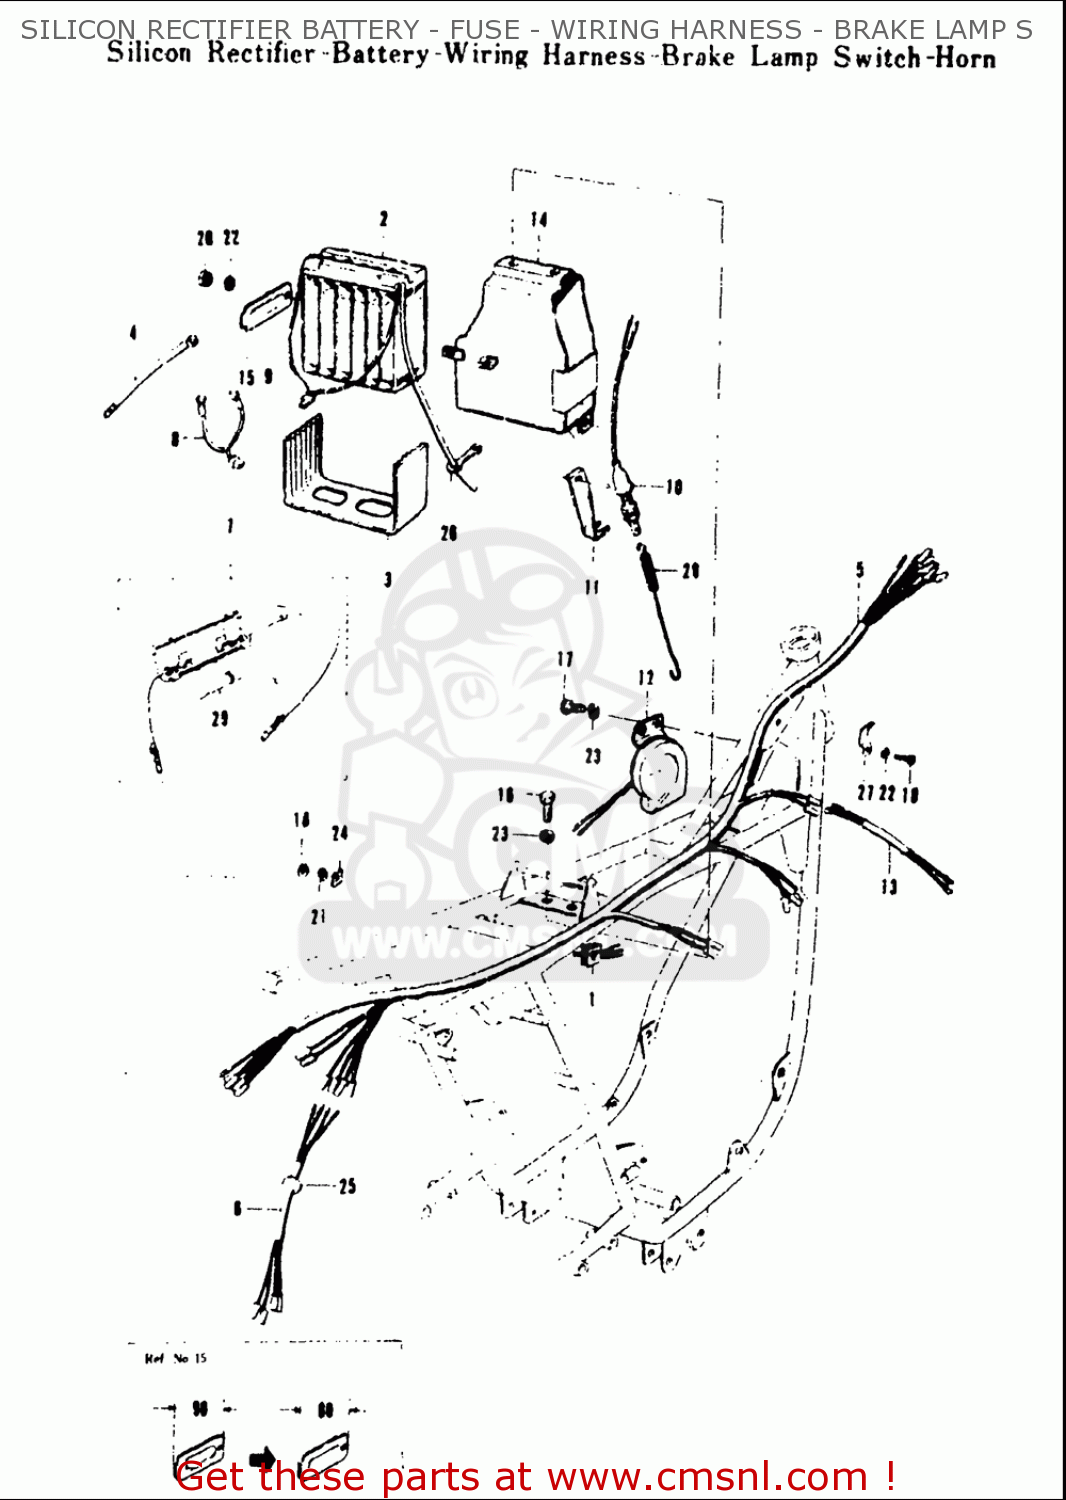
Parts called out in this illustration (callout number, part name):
1	RECTIFIER ASSY
2	BATTERY ASSY(YB5L-B,12V5.3AH)
7	CASE ASSY,FUSE
12	HORN ASSY
16	BOLT
17	BOLT
18	SCREW
19	NUT
20	NUT
21	WASHER,LOCK
22	WASHER,LOCK
23	WASHER,LOCK
28	SPRING
29	FUSE(15A)
